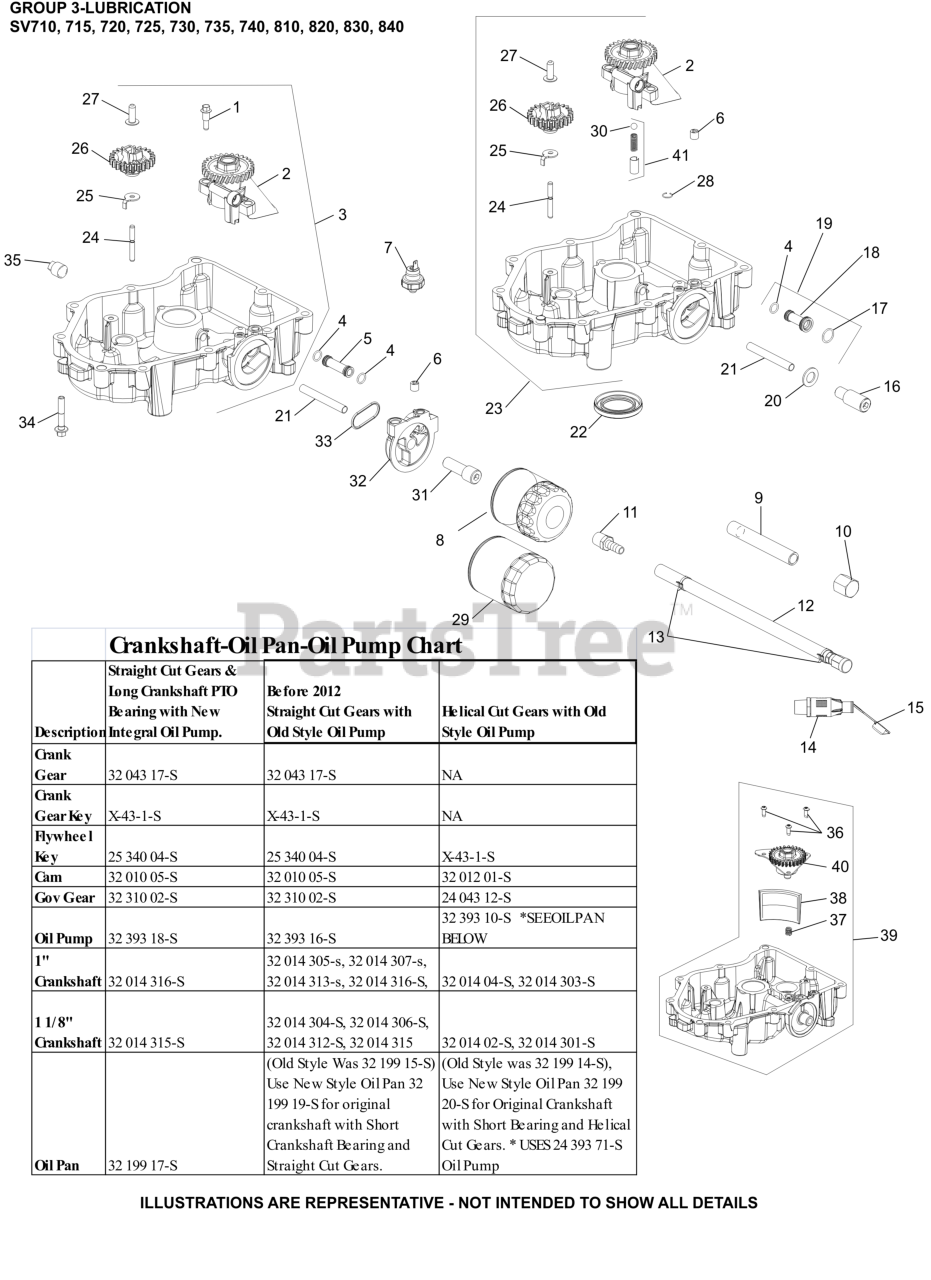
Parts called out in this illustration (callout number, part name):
2	PUMP, OIL ASSEMBLY-DISCONTINUED
4	O-RING, OIL PICK-UP
6	PLUG, CTSK PIPE 1/8"
8	OIL FILTER
16	NIPPLE, OIL FILTER-(#DSC)
17	O-RING
18	TUBE, OIL FEED
19	OIL FEED TUBE ASSEMBLY
20	WASHER, FLAT
21	TUBE, OIL FEED - FILTER TO PAN-(#DSC)
23	OIL PAN ASSEMBLY - (#3219920S)
24	SHAFT, GOVERNOR GEAR
25	TAB, LOCKING
26	KIT, GOVERNOR GEAR
27	PIN, GOVERNOR REGULATING
34	SCREW, FLG M8X1.25X45
35	PLUG, SQ HD PIPE 3/8"
36	SCREW, BUTTON HEAD
37	SPRING, COMPRESSION
38	SCREEN, OIL
39	PAN ASSEMBLY, OIL
40	PUMP ASSEMBLY, OIL
